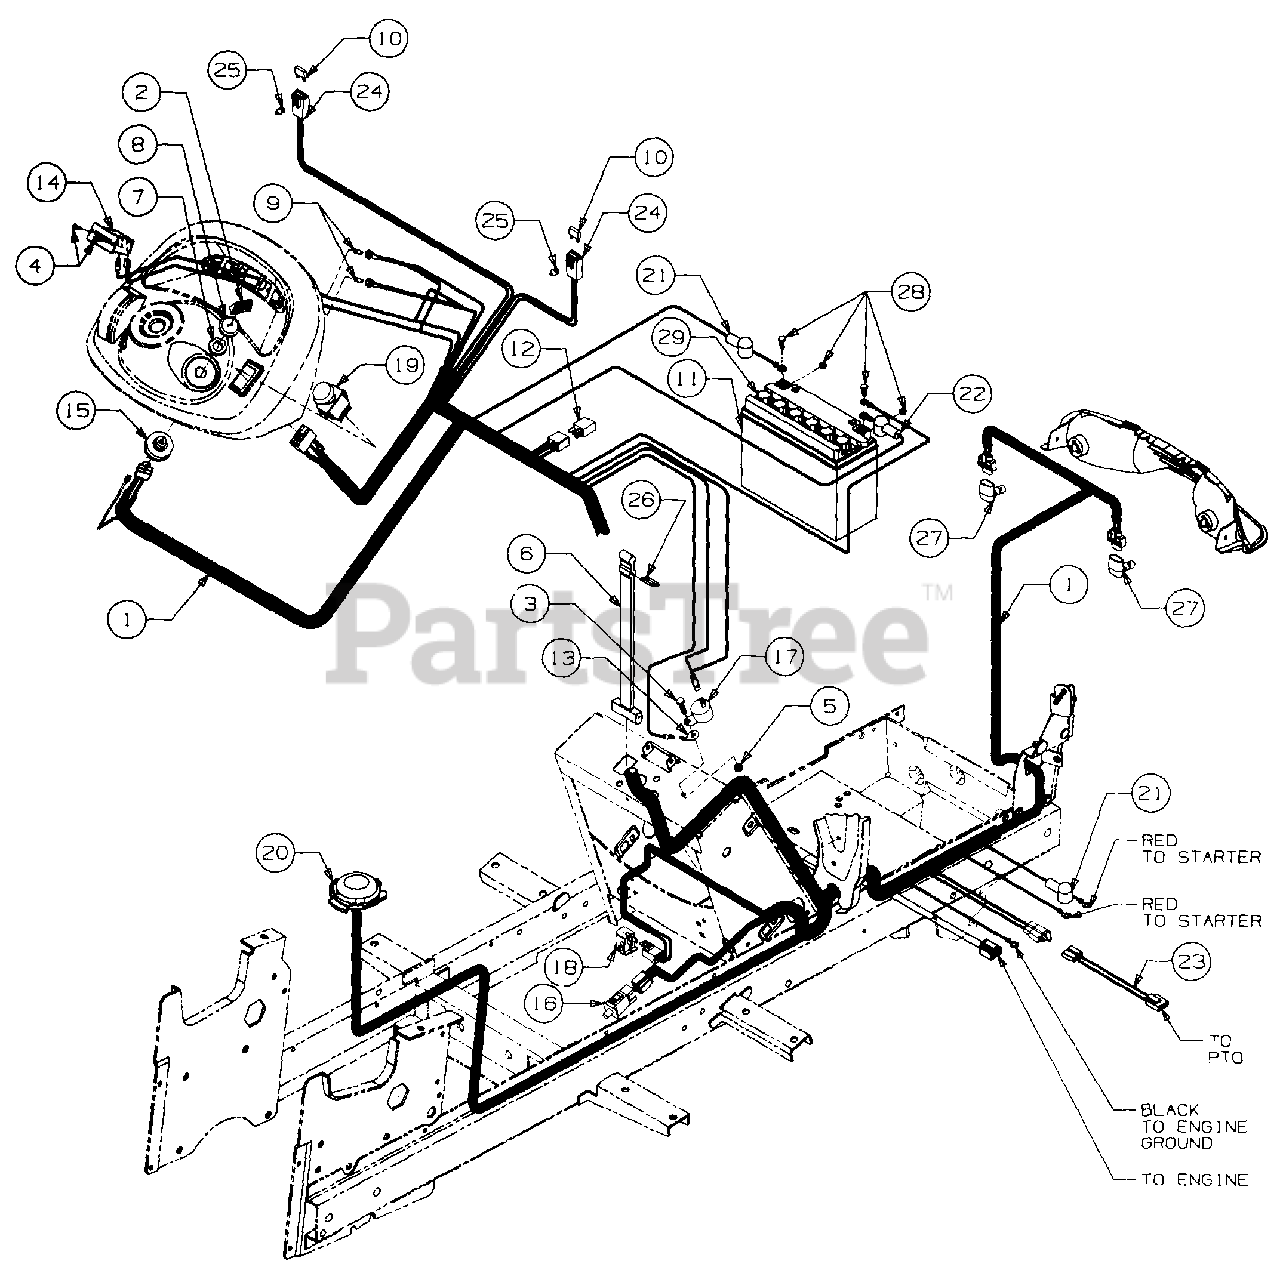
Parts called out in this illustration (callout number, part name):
1	Main Harness
2	Key, Ignition
3	Screw, Hex Cap, 1/4-20 x 1.0 Lg
4	Screw, Truss Hd Tapp, #6 x .62 Lg
5	Nut, Hex Sems, 1/4-20
6	Strap, Battery Retainer
7	Nut, Ignition Switch
8	Cap, Ignition Switch
9	Bulb, Indicator
10	Fuse, 25 Amp
12	Relay
13	Lug, Quick Connect
14	Hour Meter
15	Switch, Ignition
16	Switch, Interlock (Brake)
17	Indicator, Voltage
18	Switch, Snap Mount - Normally Closed (Reverse)
19	Switch, PTO
20	Switch, Seat
21	Cover, Terminal Red
22	Cover, Terminal Black
23	Adapter, PTO Harness
24	Holder, Fuse
25	Clip, Fuse Holder Mtg
26	Hook, Wire Rectangular
27	Bulb, Head Lamp
28	Bolt, Battery
29	Cap, Battery
